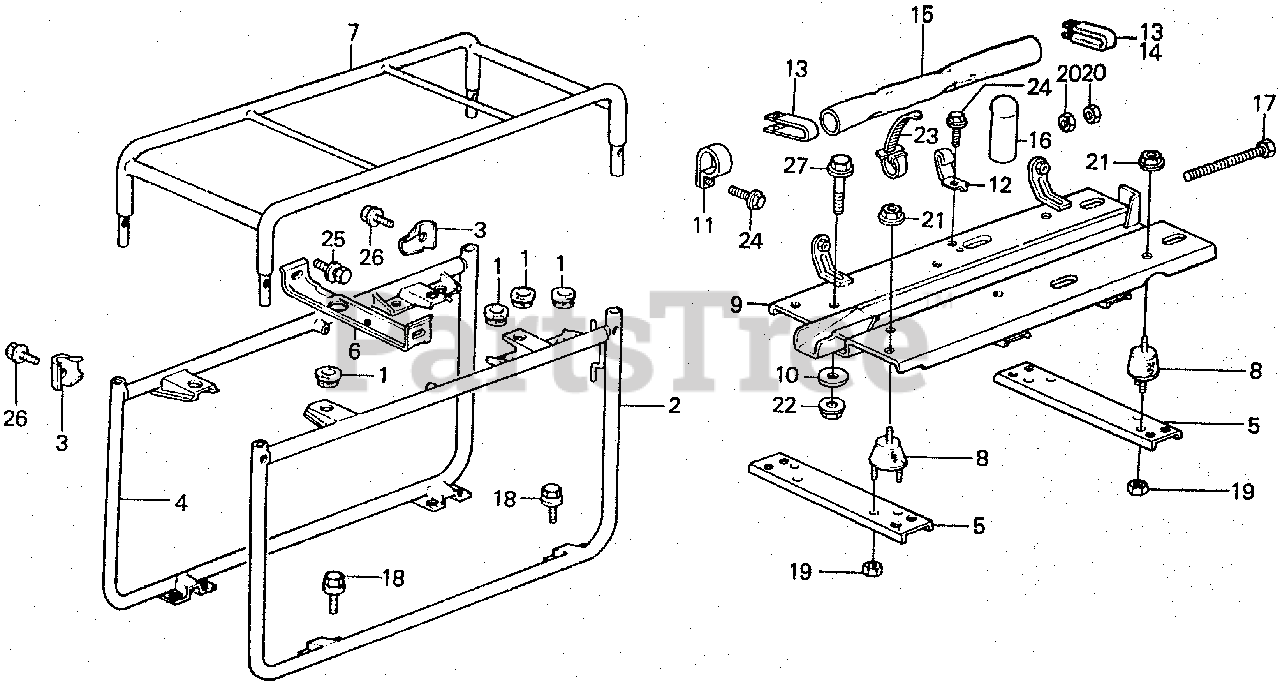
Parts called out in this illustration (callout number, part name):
1	RUBBER, TANK CUSHION
2	FRAME, FR. PIPE
3	PLATE, JOINT
4	FRAME, RR. PIPE
5	PLATE (LOWER)
6	STOPPER, ENGINE
7	GUARD, FUEL TANK (NOT AVAILABLE)
8	RUBBER, ENGINE SETTING
9	BED, ENGINE
10	WASHER, EX. MANIFOLD
11	CLIP, WIRE
12	CLIP, WIRE
14	CLIP, CORD
15	TUBE, WIRE
16	TUBE, CORD (25MM)
17	BOLT, HEX. (8X80)
18	BOLT-WASHER (8X16)
19	NUT, HEX. (6MM)
20	NUT, HEX. (8MM)
21	NUT, FLANGE (8MM)
22	NUT, FLANGE (10MM)
23	BAND B1, WIRE
24	BOLT, FLANGE (6X12)
25	BOLT, FLANGE (6X12)
26	BOLT, FLANGE (8X16)
27	BOLT, FLANGE (10X50)
